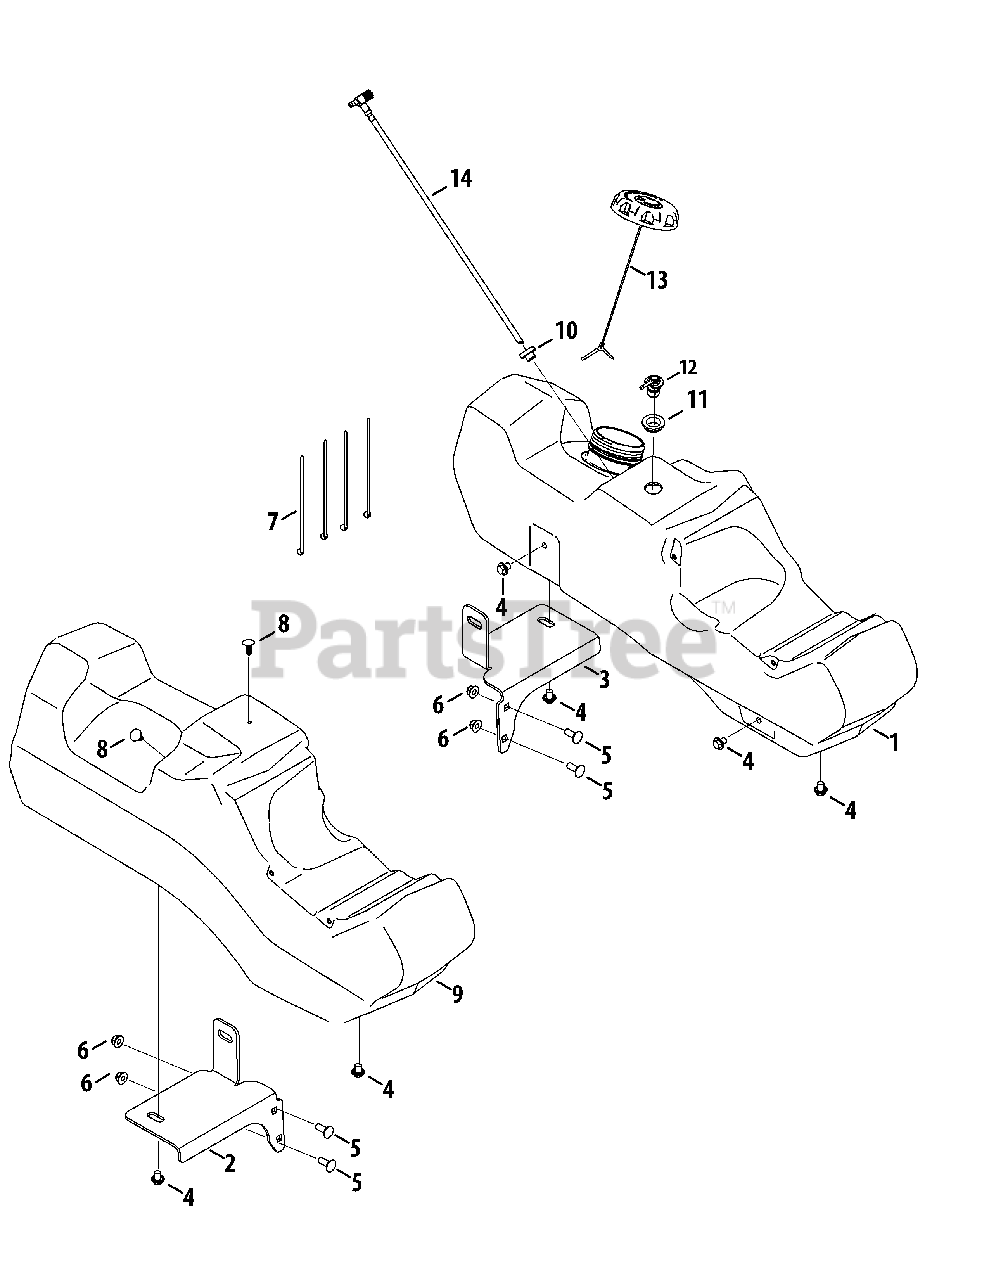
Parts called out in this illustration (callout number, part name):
1	Fuel Tank Assembly, LH
2	Rear Fuel Bracket, RH
3	Rear Fuel Bracket, LH
4	Hex Cap Screw, 3/8-16 x .500
5	Carriage Bolt, 3/8-16 x .500
6	Nut, 3/8-16, Flangelock
7	Cable Tie
8	Clip, .250 Dia.
9	Console, RH
10	Fuel Tank Grommet
11	Grommet, .755 x .955 x .55
12	Fuel Rollover Valve
14	Fuel Pickup Valve
